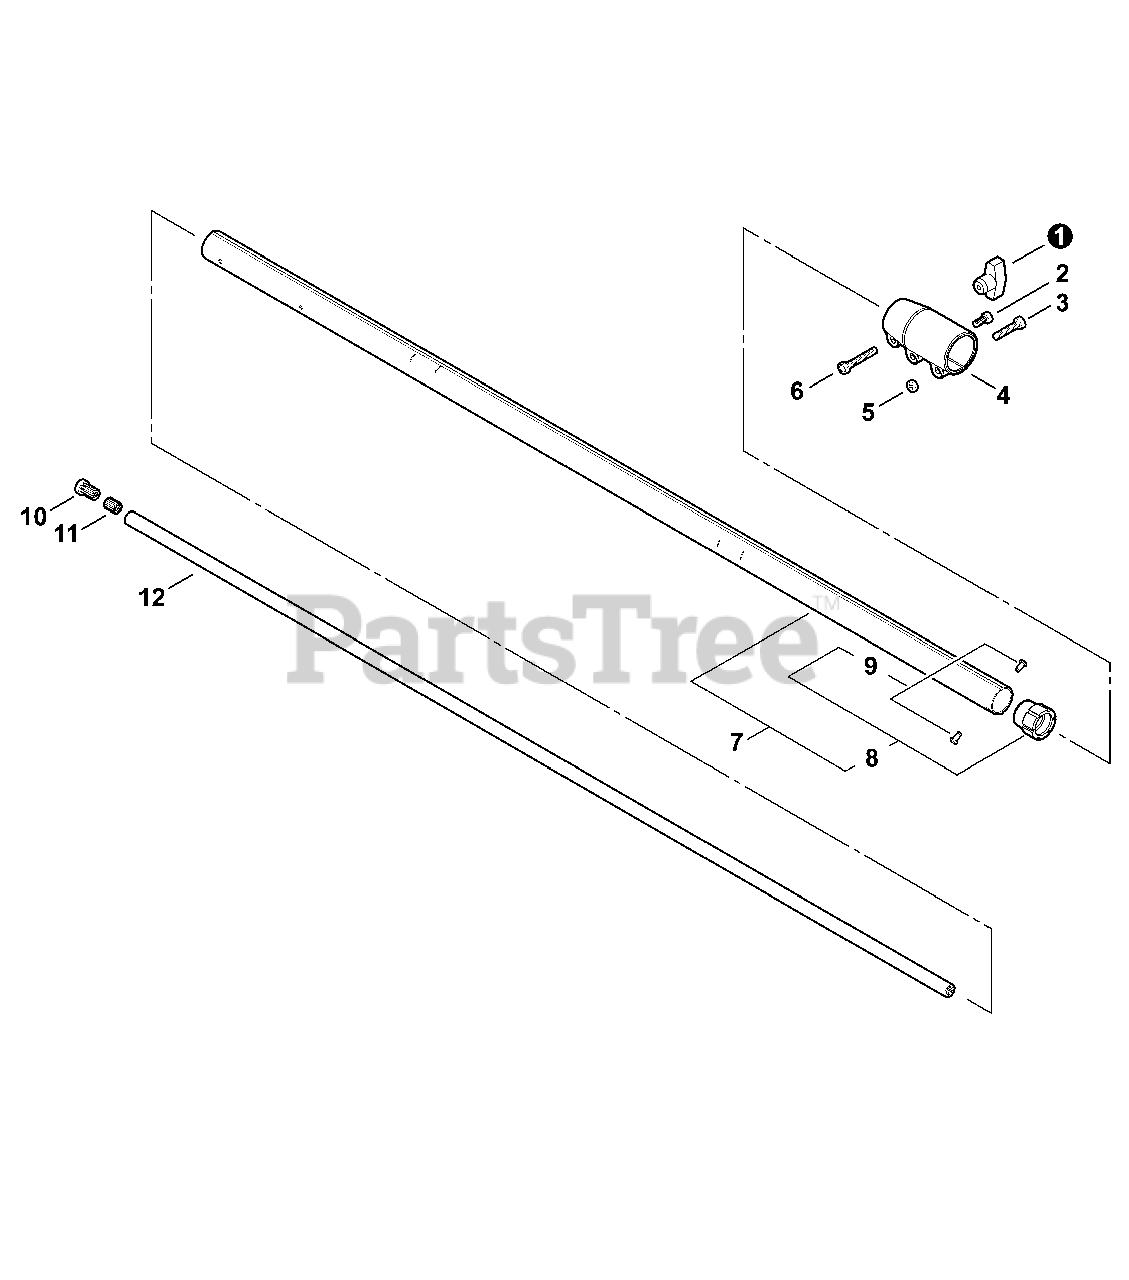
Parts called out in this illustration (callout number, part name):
1	THUMBSCREW
2	BOLT 5×12
3	BOLT 5×20
4	COUPLING
5	NUT M5
6	BOLT 6×25
7	MAIN PIPE ASSY - BLACK
8	HOLDER ASSY, BEARING
10	SOCKET - OUTER
11	SOCKET - INNER
12	DRIVESHAFT - UPPER
